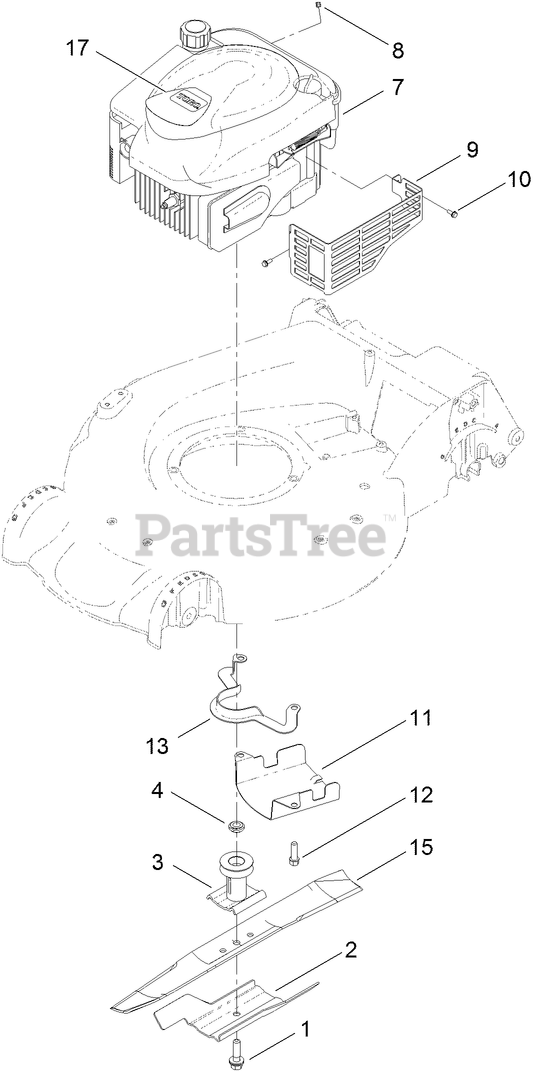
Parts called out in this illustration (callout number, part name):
2	ACCELERATOR-BLADE
3	DRIVER-BLADE
4	SPACER-DRIVER
8	STOP-ROPE
9	SHIELD-MUFFLER
10	SCREW-TAPTITE
11	SHIELD-GRASS
12	SCREW-TAPTITE
13	GUIDE-BELT
17	DECAL-SHROUD
